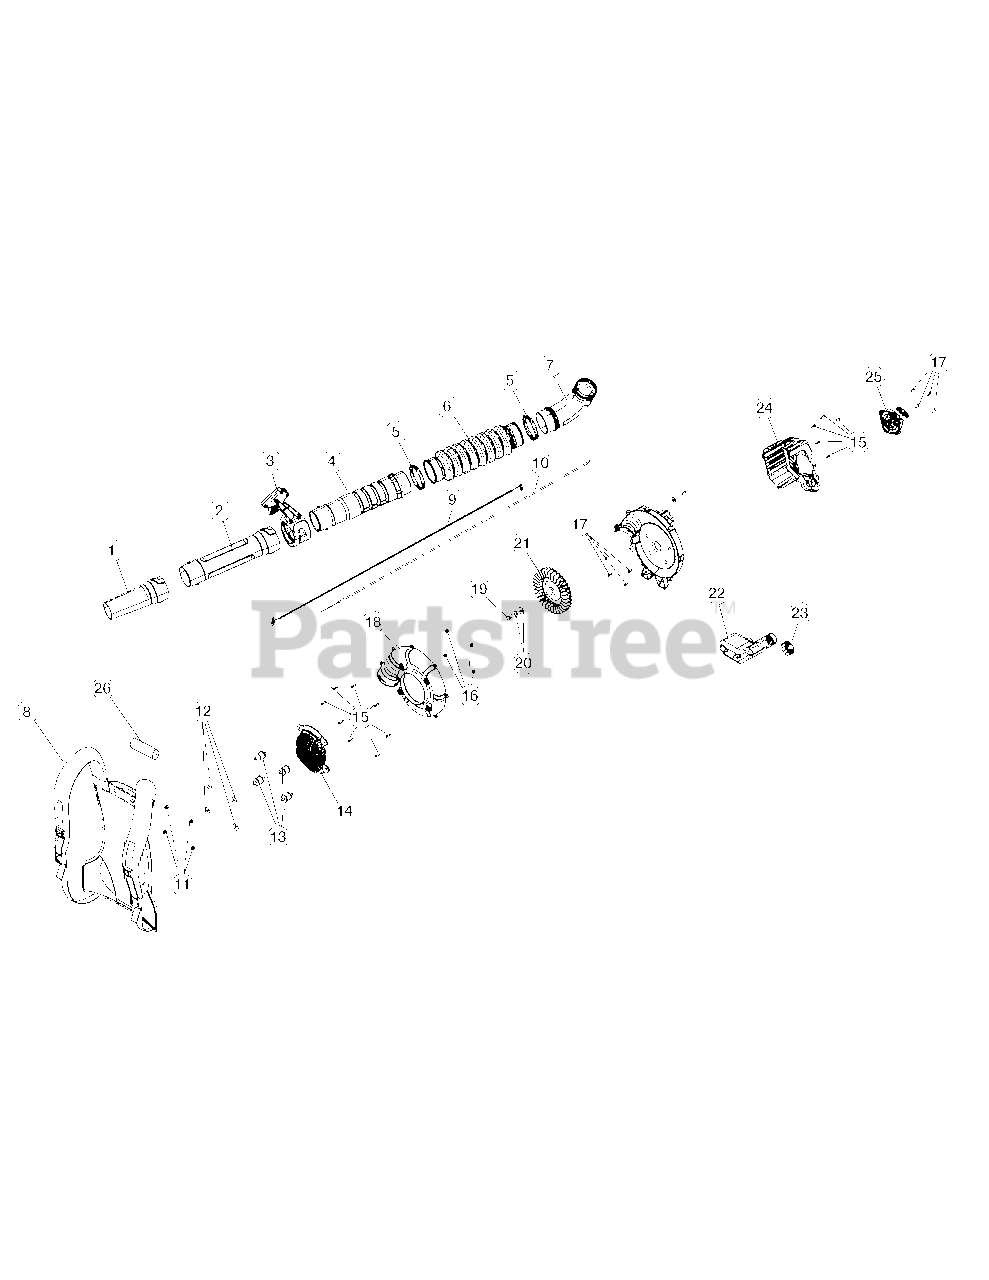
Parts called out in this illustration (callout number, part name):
2	Lower Blower Tube
3	Throttle Grip Assembly
4	Upper Blower Tube
10	Throttle Cable
11	Nut
12	Washer
13	Insulator Mount
14	Intake Cover
17	Screw
18	Impeller Housing Assembly (Incl. 13-17)
20	Impeller Hardware (Incl. 19)
21	Impeller (Incl. 19 & 20)
22	Fuel Tank Assembly (Incl. 23)
24	Housing Assembly (Incl. 15)
25	Starter Assembly (Incl. 17)
